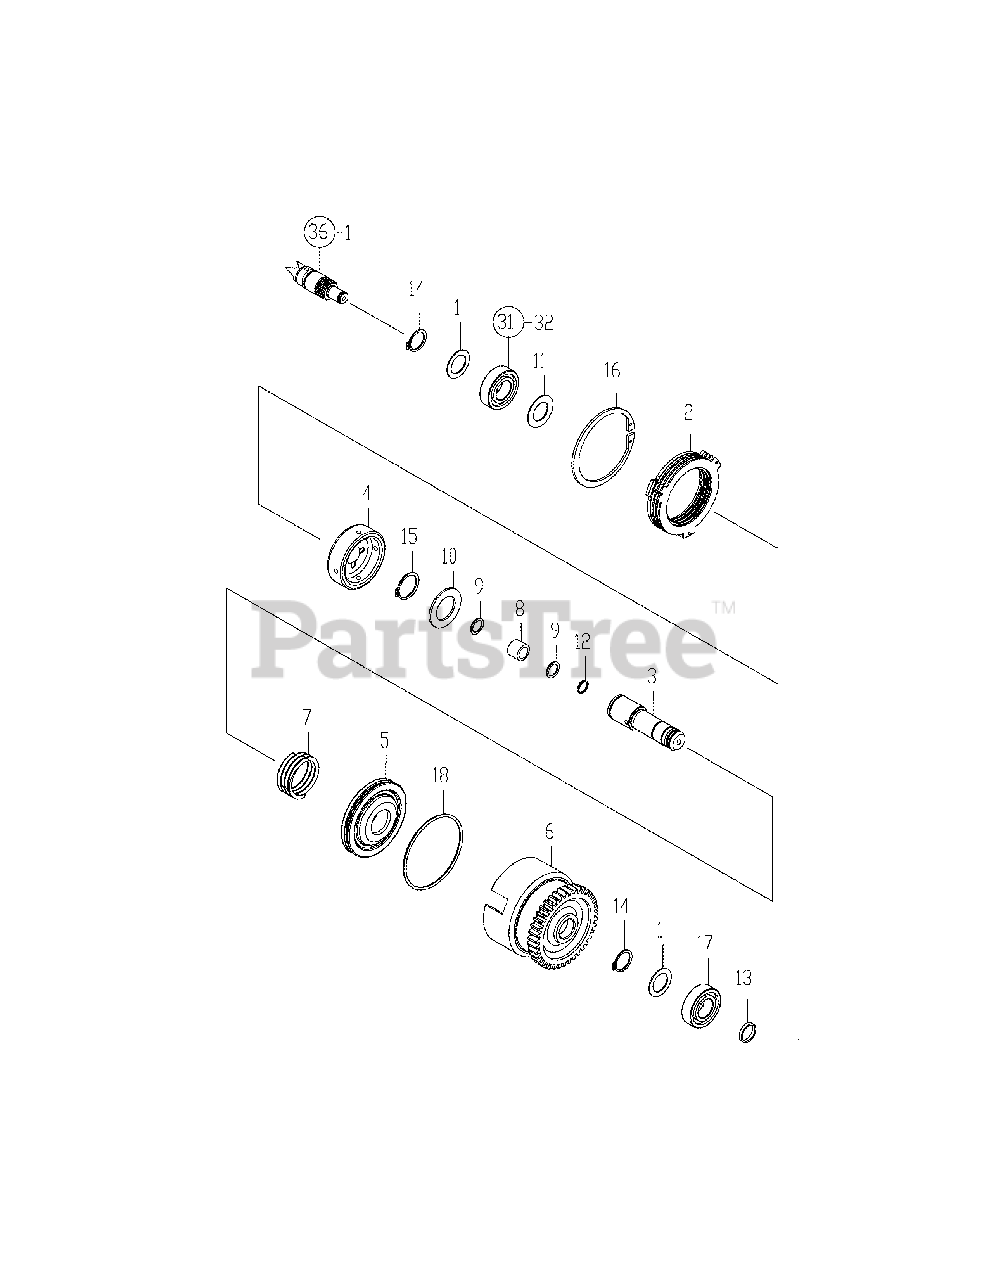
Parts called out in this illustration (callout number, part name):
2	Disc Kit, Friction
4	Collar, Spline
6	Gear, Clutch Z=39
7	Spring, Pto Return
8	Needle, 121718
9	Washer, 13X17X1
10	Washer, 25X42X2
11	Washer, 20X34X1
13	Ring, Seal 17203
18	Packing, G 75.0
